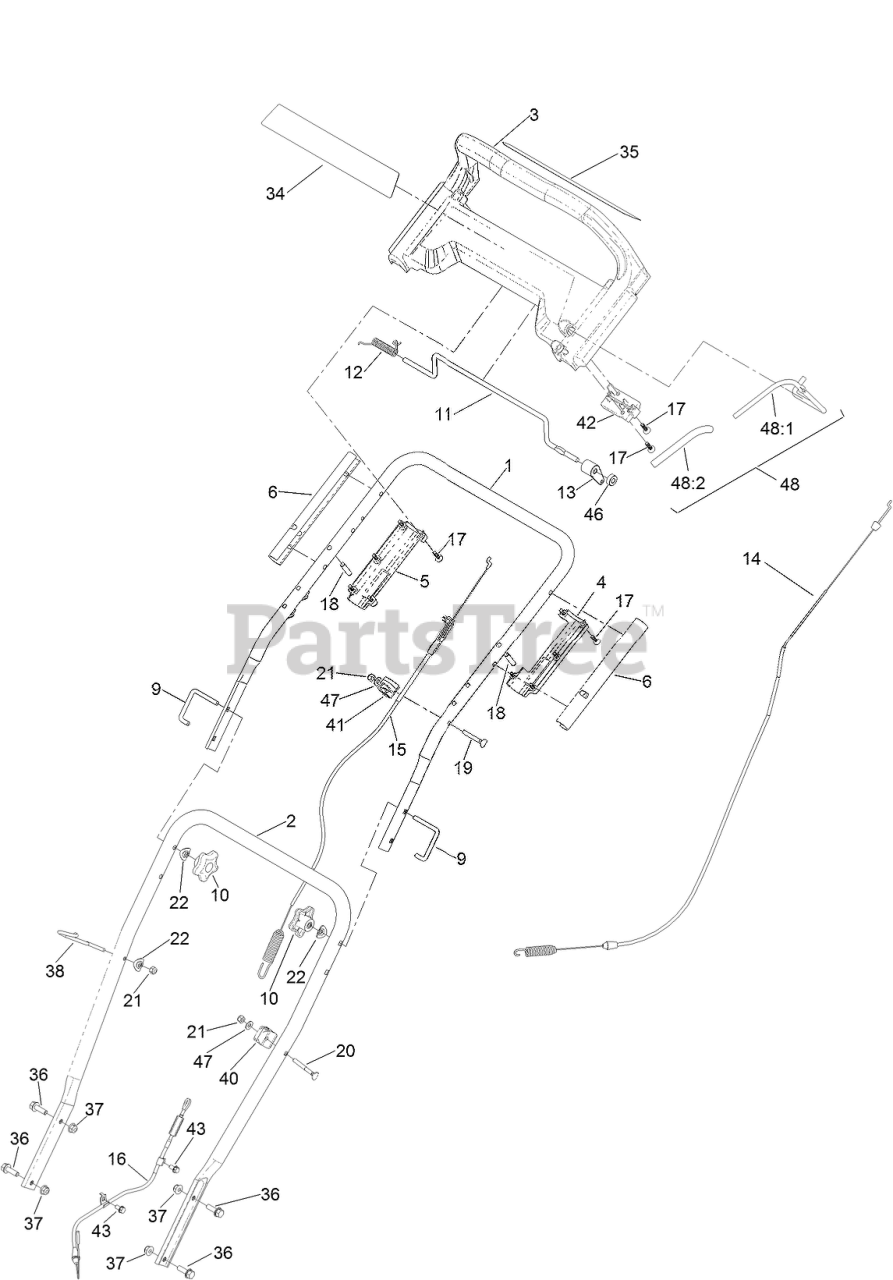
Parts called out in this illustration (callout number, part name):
1	HANDLE-UPPER
2	HANDLE-LOWER
3	HANDLE
4	HANDLE-BOTTOM, LH
5	HANDLE-BOTTOM, RH
6	SLEEVE HANDLE
9	LOCK-HANDLE
10	KNOB-HANDLE
11	BAR-CONTROL, TRACTION
12	Spring-Torsion
13	LEVER-TRACTION
14	CABLE-TRANSMISSION
15	CABLE-ROTOR, UPPER
16	CABLE-ROTOR, LOWER
18	PIN-DOWEL
19	SCREW
20	SCREW-HANDLE
21	NUT-LOCK, NI
22	WASHER
34	DECAL-DISPLAY
35	DECAL-CONTROL, PANEL
36	SCREW-HHF
37	NUT-HF, NI
38	GUIDE-ROPE
40	ANCHOR-CABLE, UPPER
41	CABLE-GUIDE
42	BAIL-MOUNT
43	SCREW-HWH
46	SPACER
47	WASHER-FLAT
48	BAIL ASM
48:1	BAIL-AUGER
48:2	COVER-BAIL
